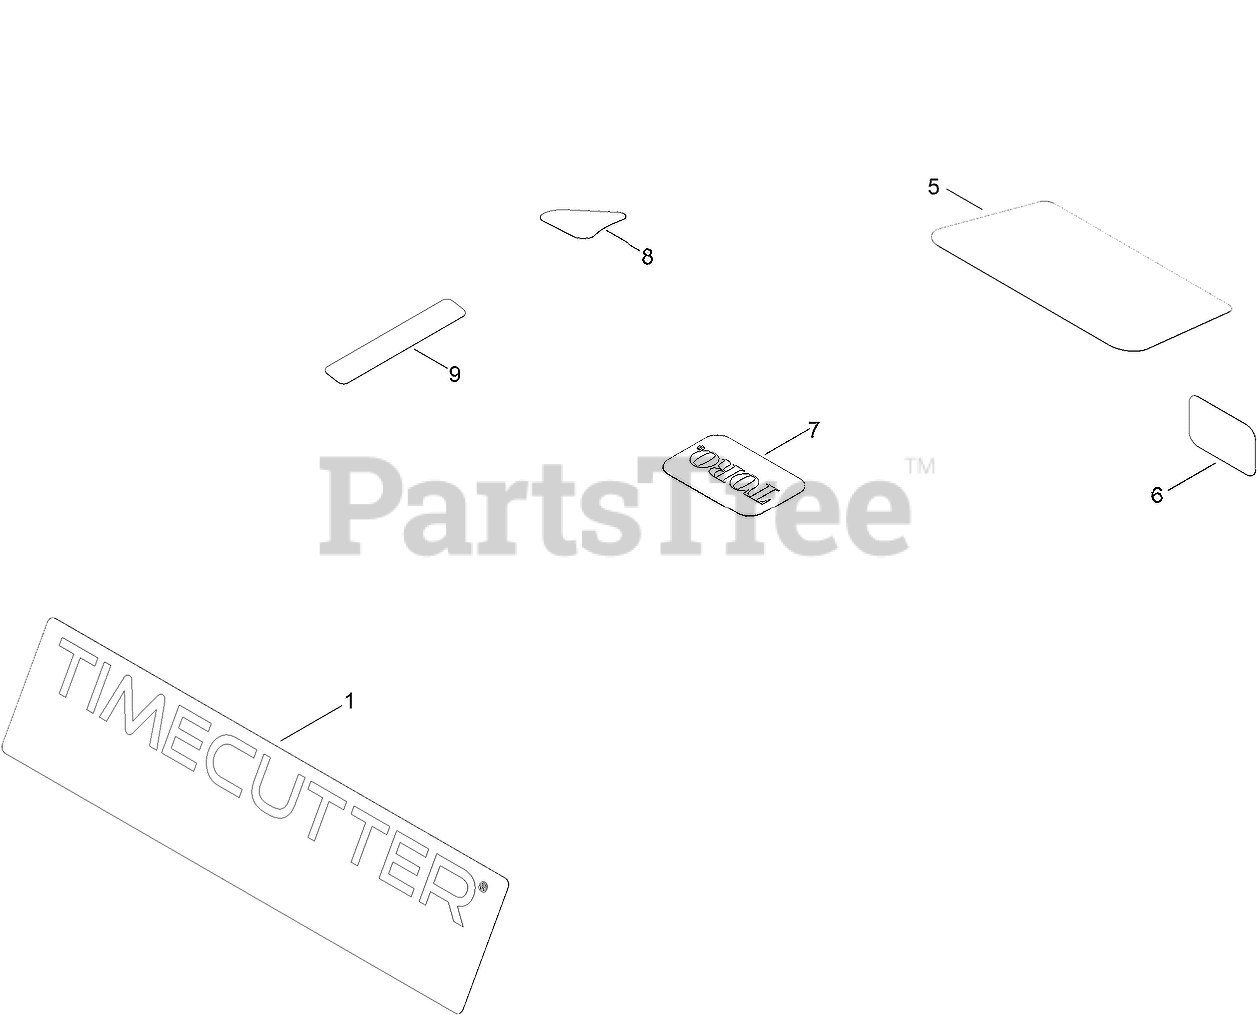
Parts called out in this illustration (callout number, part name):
1	DECAL-TIMECUTTER
5	DECAL-ENGINE
6	PLACARD-INTAKE
8	DECAL-DRAIN, OIL
9	DECAL-SHUTDOWN
